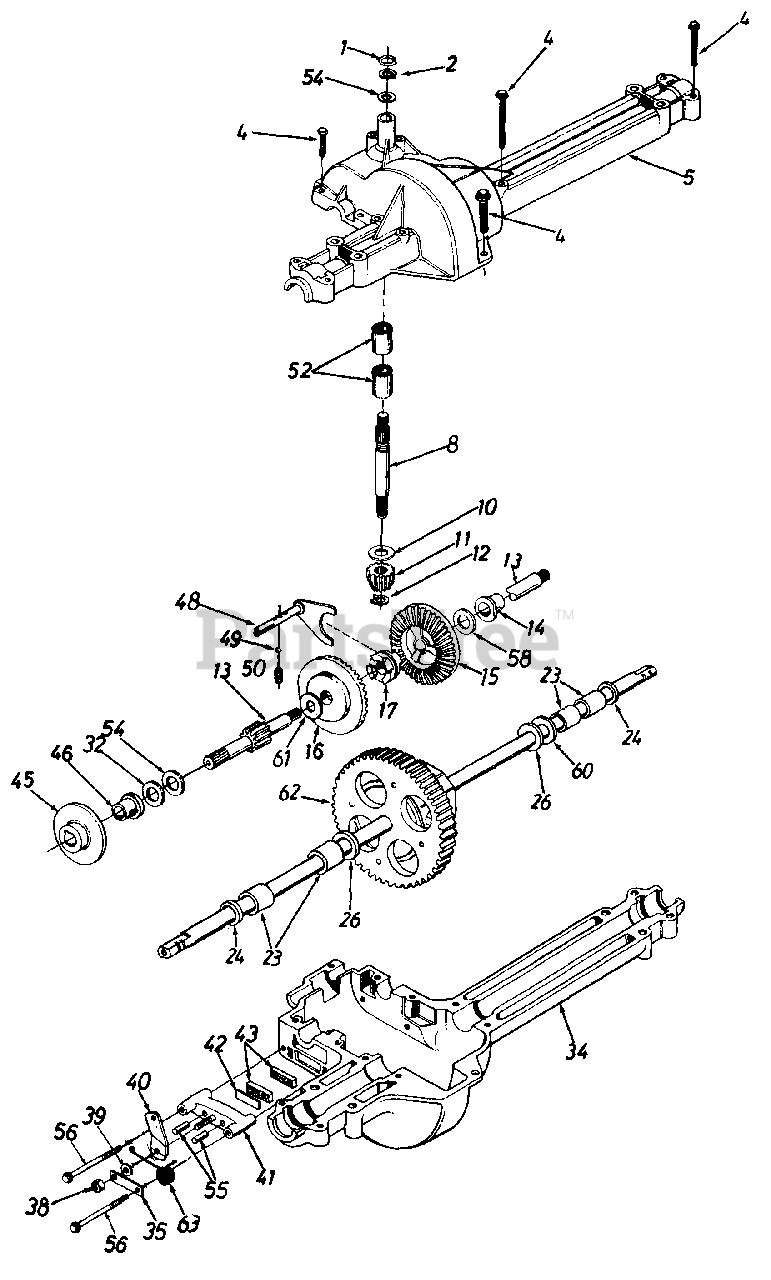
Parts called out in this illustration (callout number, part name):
2	Retaining - Ring
4	Scritt 1/4-20 x 1.625
5	Upper Housing
10	Thrust Washer 5/8" I.D. x 1.25" O.D.
11	Pinion Input 14T
12	Retaining Ring
13	Drive Shaft - L.H. Brake
14	Flange Brg. 5/8" I.D. x 3/4" Lg.
15	Bevel Gear 42T Small I.D.
16	Bevel Gear 42T Large I.D.
17	Clutch Collar
23	Sleeve Bearing 3/4" I.D. x 1.0" Lg.
24	Oil Seal 3/4" I.D.
26	Fl-Wash. .760" I.D. x 1.5" O.D.
32	Thrust Wash. 5/8" I.D. x 1" O.D. x .025" Thk.
34	Lower Housing
35	Anti-Rotation Brkt.
38	Hex Nut 5/16-24 Thd.
39	Fl-Wash. .344" I.D. x .875" O.D.
40	Actuating Arm
41	Brake Yoke
42	Puck Plate
43	Brake Puck
46	Flange Bearing 5/8" I.D. x 15/16" Lg.
48	Shift Fork Ass'y.
49	Ball Detent .250" Dia.
50	Spring Detent
52	Needle Brg. 5/8" I.D. x 1/2" Lg.
54	Fl-Wash. 5/8" I.D. x 1" O.D. x .020 Thk.
55	Actuating Pin 5/16" Dia.
56	Hex Wash Hd. Self-Tap Scr. 1/4-20 Thd.
58	Fl-Wash. 5/8" I.D. x 1" O.D. x .020 Thk.
60	Fl-Wash. .76" I.D. x 1.5" O.D. x .010" Thk.
61	Thrust Washer
62	Differential Ass'y.
63	L.H. Brake Spring
